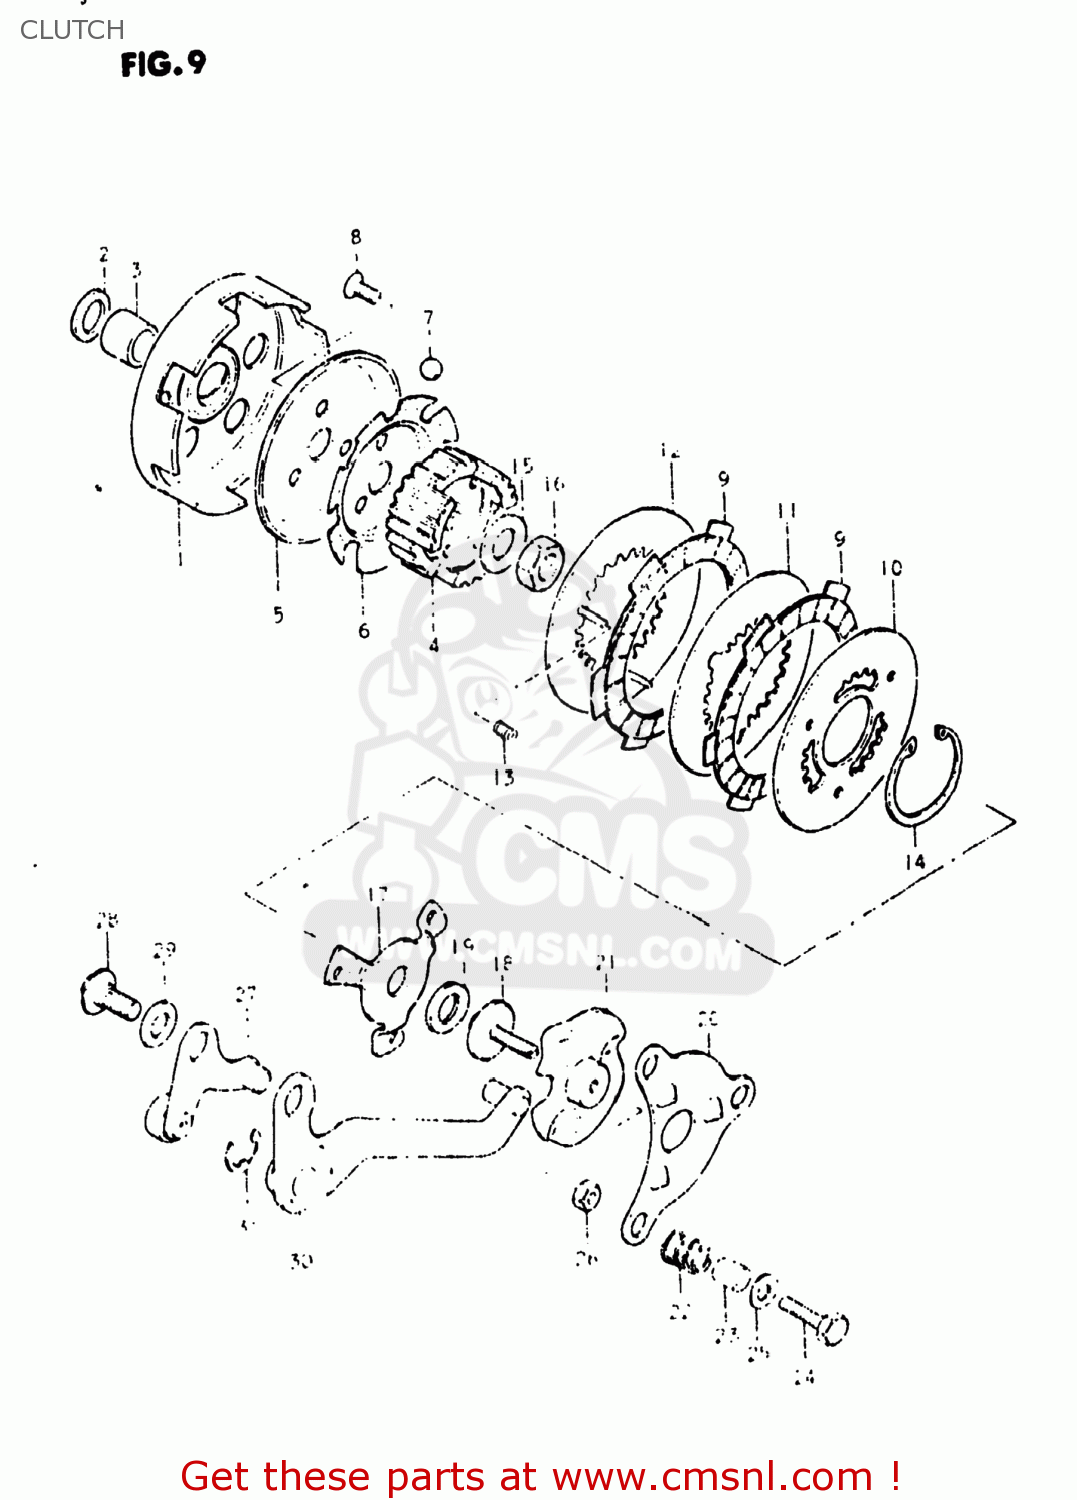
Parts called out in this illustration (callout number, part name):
1	GEAR,PRIMARY DRIVE
2	WASHER(14X23X3)
3	SPACER(14X19X18)
4	HUB,CLUTCH SLEEVE
5	PLATE,CLUTCH BALL
6	GUIDE,CLUTCH BALL
7	BALL
8	SCREW
9	PLATE,CLUTCH DRIVE (NAS)
10	PLATE,CLUTCH DRIVEN OUTER (NAS)
11	PLATE,CLUTCH DRIVEN (NAS)
12	PLATE,CLUTCH INNER
13	SPRING
14	CIRCLIP
15	WASHER
16	NUT
17	PLATE,CLUTCH PRESSURE
18	PIECE,CLUTCH PUSH
19	BEARING(10X22X2.8)
20	PLATE,CLUTCH RELEASE
21	PLATE,CLUTCH RELEASE,INNER
22	SPRING
23	SPACER(6X9X10.3)
24	BOLT
25	WASHER
26	NUT
27	PLATE,CLUTCH RELEASE ARM LINK
28	BOLT(8X17)
29	WASHER
30	ARM,CLUTCH RELEASE PLATE
31	E RING
